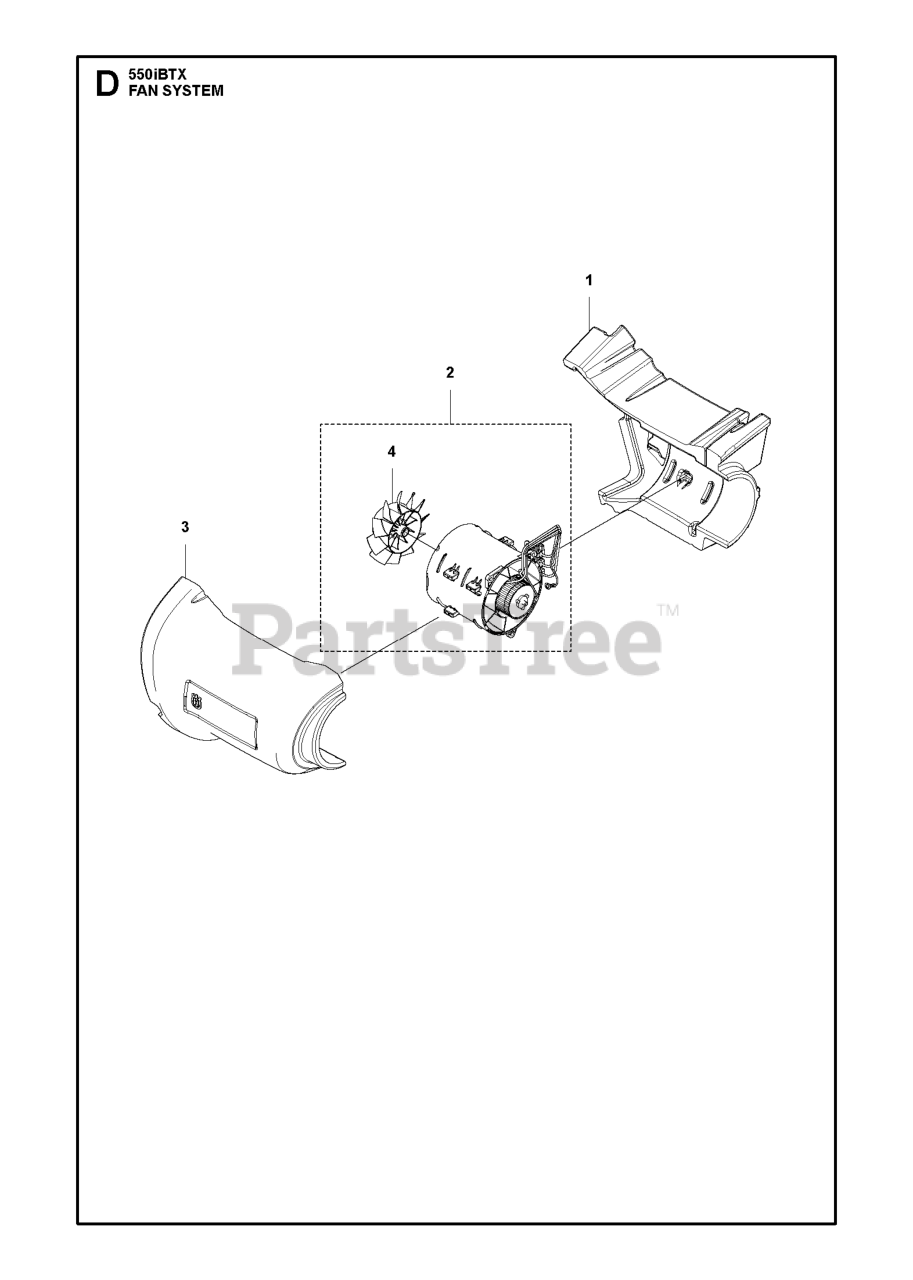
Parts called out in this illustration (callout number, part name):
1	MUFFLER ASSY INNER 550IBTX
2	FAN SYSTEM
3	MUFFLER ASSY OUTER 550IBTX
